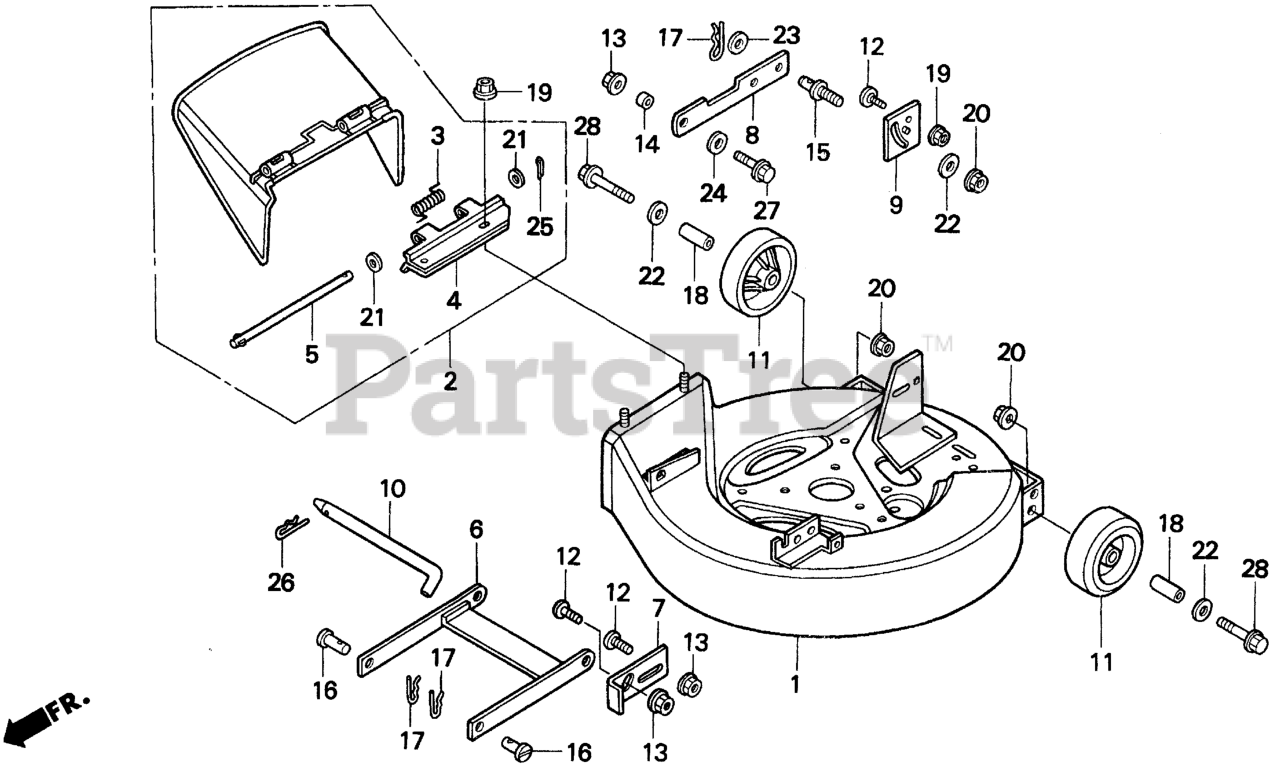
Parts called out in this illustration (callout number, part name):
1	HOUSING, CUTTER
2	ADAPTER, DISCHARGE *NH1* (BLACK)
3	SPRING, DISCHARGE ADAPTER
4	HINGE, DISCHARGE ADAPTER
5	PIN, DISCHARGE ADAPTER (NOT AVAILABLE)
7	PLATE, FR. LINK ADJUSTMENT
8	LINK, RR. DECK
9	PLATE, RR. LINK ADJUSTMENT
10	SHAFT, FR. LINK
11	ROLLER, ANTI-SCALP
12	BOLT, SPECIAL (8X20)
13	NUT, FLANGE (8MM)
14	COLLAR, MUFFLER MOUNTING
15	PIN, LINK A
18	COLLAR, ANTI-SCALP
19	NUT, FLANGE (8MM)
20	NUT, FLANGE (10MM)
21	WASHER, PLAIN (6MM)
22	WASHER, PLAIN (10MM)
23	WASHER, PLAIN (14MM)
24	WASHER, PLAIN (8MM)
25	PIN, COTTER (2.0X12)
26	PIN, LOCK (16MM)
27	BOLT, FLANGE (8X25)
28	BOLT, FLANGE (10X55)
